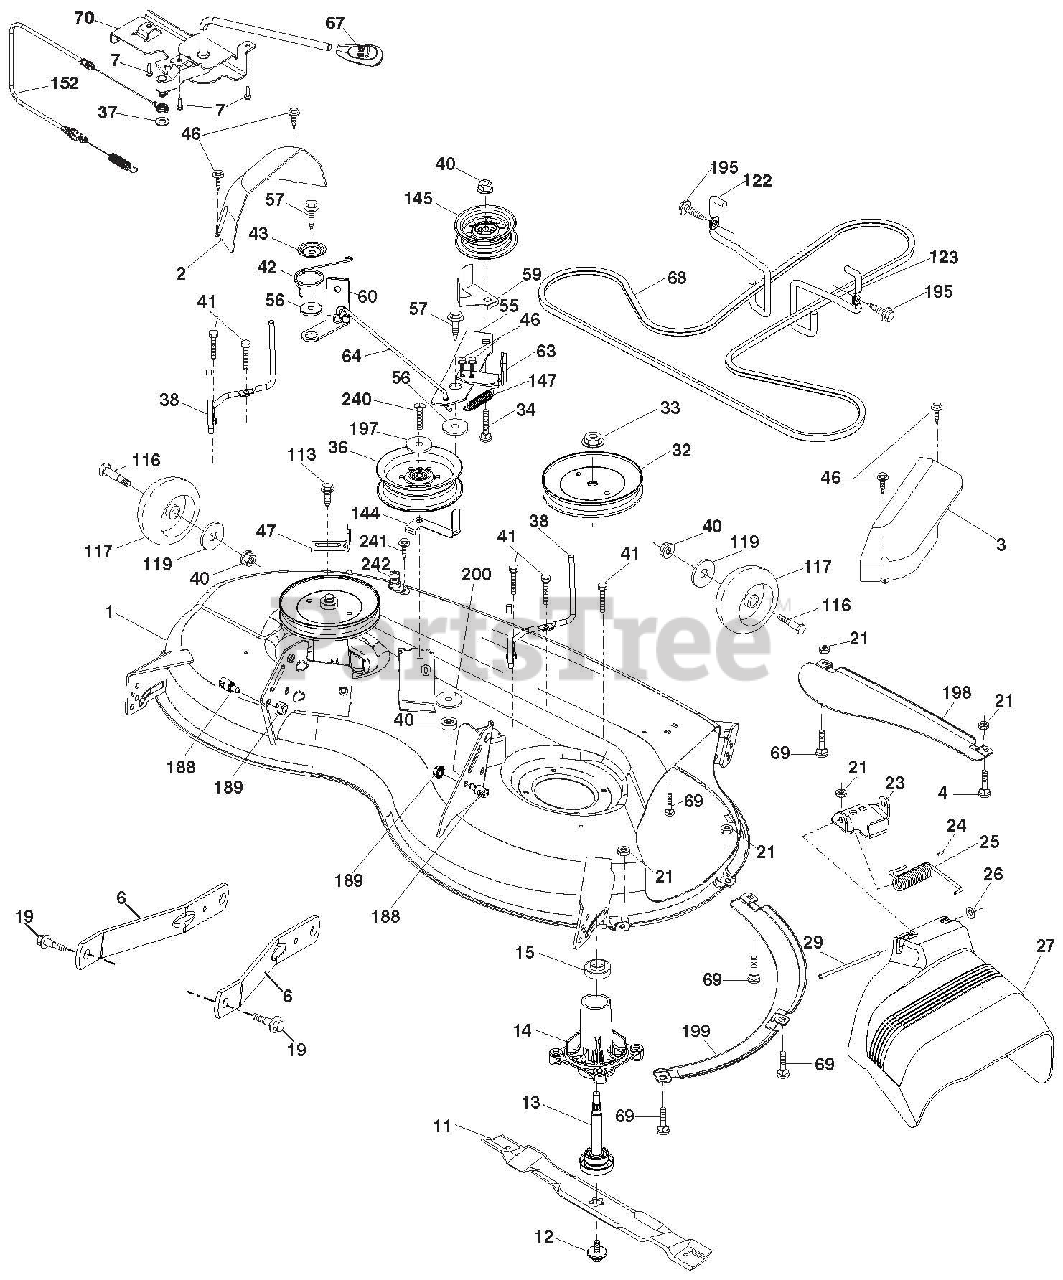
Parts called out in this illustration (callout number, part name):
1	MOWER.HOUSING
2	COVER.MANDREL.LH.46"
3	COVER.MANDREL.RH.46"
4	BOLT.HEX.HD.1/4-20UNC X 3/4
6	ARM.SUSPENSION.MOWER.REAR.LD
11	BLADE.MOWER.46"HI LIFT BAGGER
12	SCREW 7/16-20 X 1
13	SHAFT ASM
14	HOUSING.MANDREL.4PT.SERVICE
15	BEARING
19	BOLT.SHOULDER
21	Nut, Hex, Crownlock 5/16-18
23	BRACKET.DEFLECTOR.38/42"2005
24	CAP.SLEEVE..80X.112.BLK.MOWER
25	SPRING.TORSION.DFL.38/42/46.GR
26	NUT.PUSH.PHOS.& OIL
27	SHIELD.DEFLECTOR.MOWER 46"BLK
29	ROD.HINGE.42/46"
30	SCREW.THD ROLL.DOD PT.HEX
32	PULLEY.MANDREL.5.438 PD.42"
32	MANDREL ASM
33	NUT.FLANGE.LOCK.TOP
34	BOLT.CARR.SH.3/8-16X1-1/2.GR5
36	PULLEY.IDLER.4.50.RAW
37	WASHER.13/32 X 13/16 X 16 GA.
38	KEEPER.BELT.MANDREL.PULLEY
40	Nut, Hex, Flangelock 3/8-16
41	HEX HEAD BOLT
42	SPRING.TORSION.BRAKE
43	SPRING.TORSION.RETAINER
46	SCREW.THD.ROLL.1/4-20 X 5/8
47	BRACKET.CLUTCH.CABLE
55	IDLER.ARM
56	SPACER.RETAINER
57	SCREW.3/8-16X1.SMGML.TAP/R.BLK
59	GUARD.TUV.IDLER
60	ARM.BRAKE.MOWER.38/46"LH.TEX
63	ARM.BRAKE.MOWER
64	LINAGE.ASM.BRAKE
67	HANDLE.CLUTCH.CABLE.LT TEX.428
68	V-BELT.DRIVE.MWR.MECHANICL.46"
69	BOLT.5/16-18HEX.WHS.HD.LCKSERR
70	CLUTCH.ASM.MANUAL
113	BOLT.5/16-18HEX.WHS.HD.LCKSERR
116	BOLD SHLD "A" 2.41 "B" 1.66
117	WHEEL.GAGE.HALF.SPOKED
119	Washer 3/8 x 7/8 x 14 Ga.
122	KEEPER.BELT.ENGINE.LH.LT.TEX
123	KEEPER.BELT.ENGINE.RH.LT.TEX
144	KEEPER.BELT.MOWER
145	PULLEY.IDLER 48"PRIMARY
147	SPRING.RETURN.DECK.38/46"
152	CABLE.CLUTCH.MANUAL
188	STUD.FASTNER.W/'D'ANTI-ROTATIO
189	Nut, Lock Hex Flange 5/16-18 u
195	SCREW.HEXWSH THDR3/8-16X3/4.BL
197	Washer 13/32 x 13/16 x 12 Ga.
198	BAFFLE.CENTER.FRONT
199	BAFFLE.FRONT.RH
200	WASHER.13/32 X 1 X 1/2.11GAHRD
240	BOLT.FIN.HEX.3/8-16X 2-1/4 GR5
242	PORT WASHOUT
